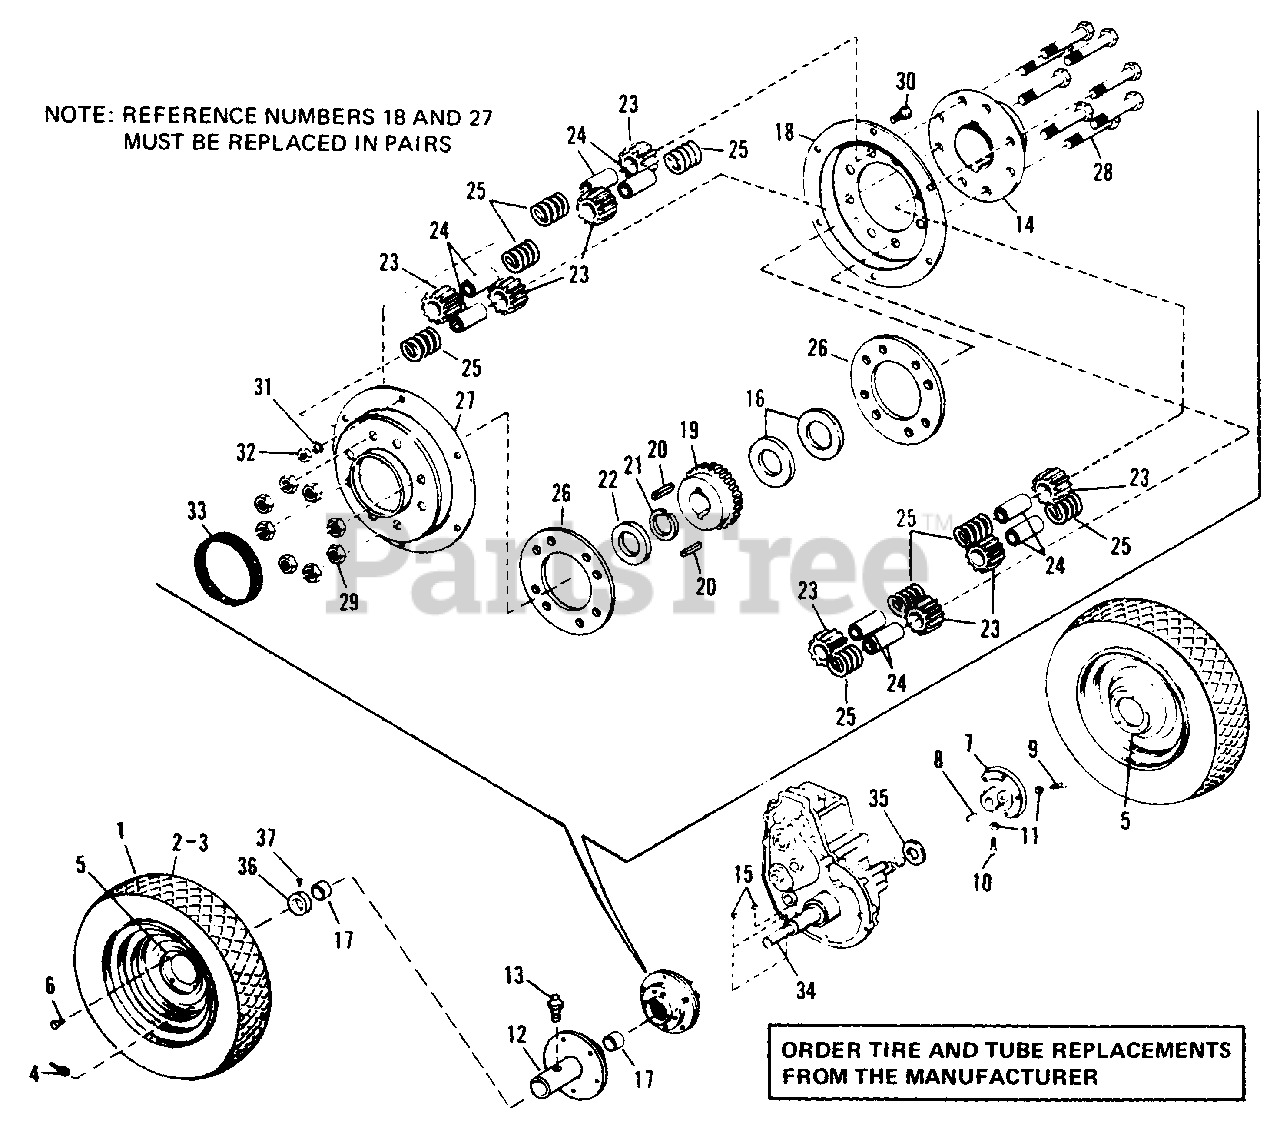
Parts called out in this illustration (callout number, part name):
1	Wheel & Tire Assy.
2	Tire 10-1/2" x 12
4	Valve Stem
5	Wheel Drive
7	Left Hand Wheel Hub
9	Set Screw, 3/8"-16 x 1-1/2"
10	SetScrew, 3/8"-16 x 1"
11	Hex Jam Nut, 3/8"-16
12	R.H. Wheel Hub Assy.
13	Grease Fitting
14	Differential Carrier
16	Axle Washer
18	Differential Cover
19	Differential Cover
20	Hi-Pro Key
21	Retaining Ring
22	Axle Washer
23	Differential Pinion
24	Differential Pinion Spindle
26	Ring Spacer
27	Differential Cover
28	Hex Capscrew, 3/8"-16 x 2-1/2"
29	Full Lock Hex, Nut, 3/8"-16
30	Hex Capscrew, 1/4"-20 x 5/8"
31	Lockwasher, 1/4"
32	Full Hex Nut, 1/4"-20
33	Differential Cover Seal
34	Rear Axle
36	Axle Collar
37	Set Screw, 5/16"-18 x 3/8"
